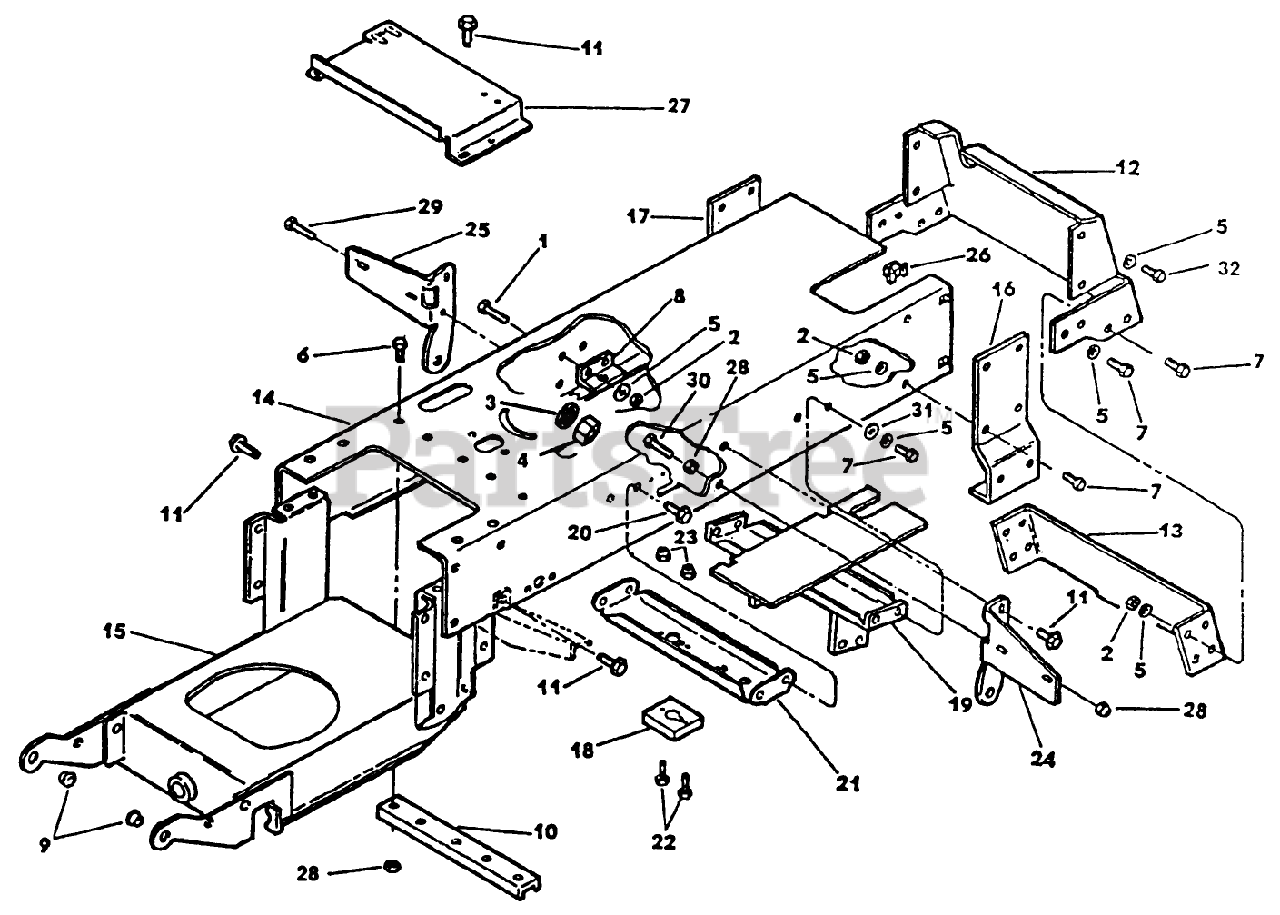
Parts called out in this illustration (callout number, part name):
2	NUT
4	NUT SS
5	WASHER
9	BEARING-NYLINER
18	BRACKET-SUPPORT *B
21	SUPPORT *B
22	SCREW
23	NUT-LOCK, CONE
25	SUPPORT - RH
27	SUPPORT, BATTERY *B
28	NUT
29	SCREW - HEX
